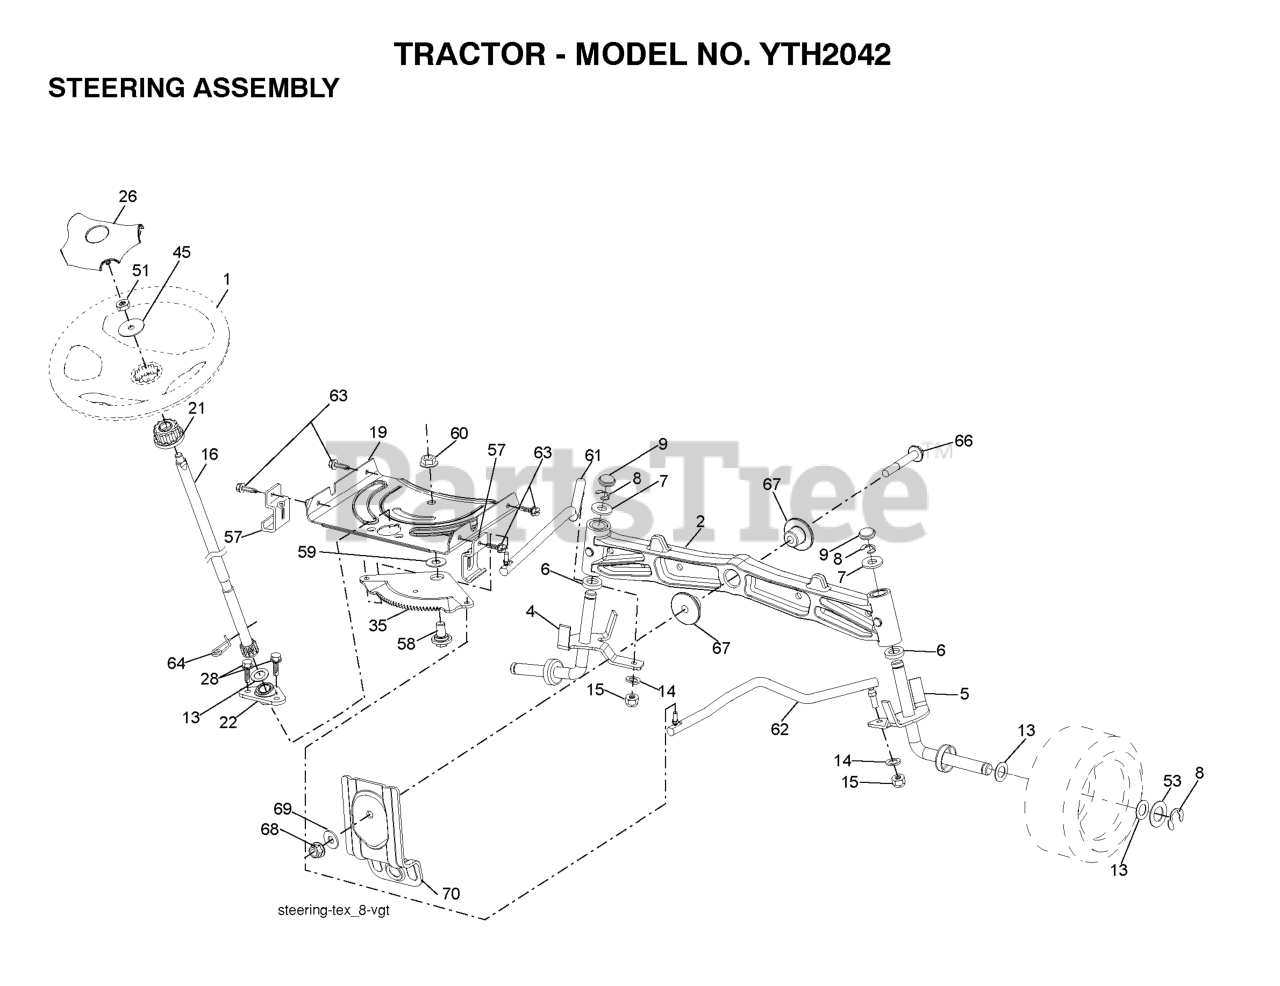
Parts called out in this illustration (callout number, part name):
1	WHEEL.STEERING.LEGEND2.GRY
2	AXLE.CAST.IRON
4	SPINDLE.WELDED.LH.15"TEX
5	SPINDLE.WELDED.RH.15"T
6	THRUST WASHER
9	CAP.SPINDLE.BLACK
14	WASHER, LOCK 3/8
15	NUT CROWNLOCK 3/8-24
16	SHAFT.STEER.STEALTH.DD
19	PLATE.STEER.DDL.NLT/NG
21	ADAPTER, WHEEL STNG..
22	BUSHING.ASM.STEERING.A
26	INSERT.CAP.STRG.WH.GRAY
28	SCREW, 3/8-16X3/4
35	GEAR.SECTOR.PLATE.DDL.
45	WASHER 9/16"ID, 2 3/8"OD
51	NUT.HEX.1/2-20
53	WASHER.HARDENED
57	BRACKET.UPSTOP.TEX
58	BOLT.SHOULDER.SECTOR.P
59	WASHER.THURST.SECTOR.S
60	NUT FLANGE LOCK 5/8-11
61	DRAGLINK.LH.BALLSTUD.D
62	DRAGLINK.RH.BALLSTUD.D
63	SCREW
64	RETAINER.CLIP.SPRING.S
66	BOLT HEX FGHD 7/16-14 X 3 SERR
67	BUSHING.PM.FRONT AXLE
68	NUT.LOCK.FLANGE.7/16
69	WASHER.1.5X.505X.118
70	BRKT.DECK.SUSPENSION.F
